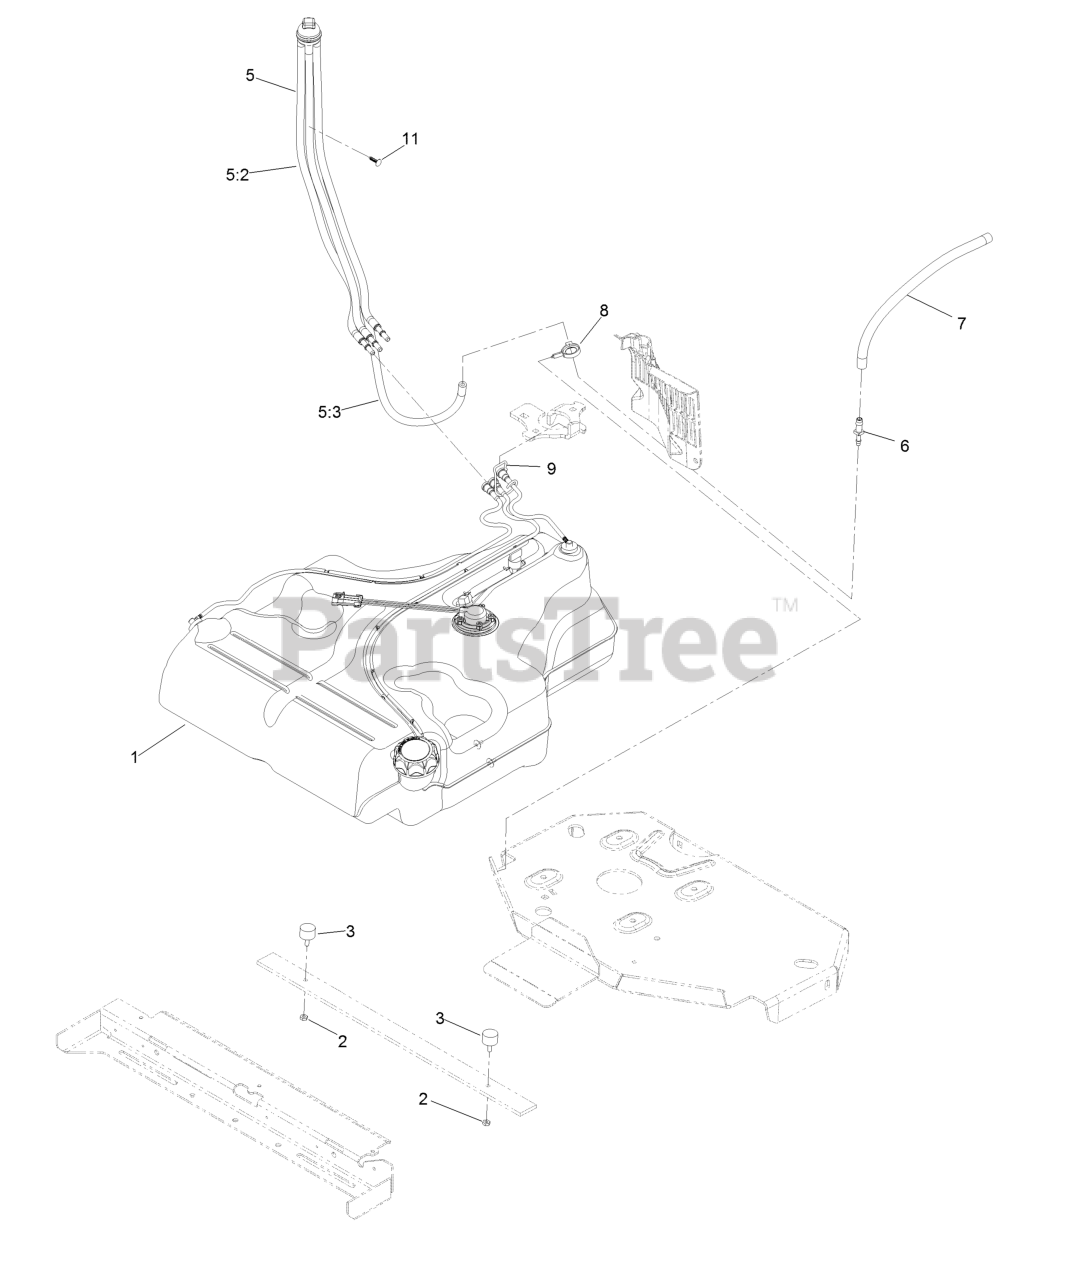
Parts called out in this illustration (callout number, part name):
1	Fuel Tank ASM
2	Nut-Jam
5	Fuel Manifold Vent ASM
5:2	Hose-Fuel
5:3	Hose-Fuel
6	Fitting-Straight
7	Hose-Fuel
8	Clamp-Hose
9	Retainer-Line, Vapor
11	Plug-Plastic
